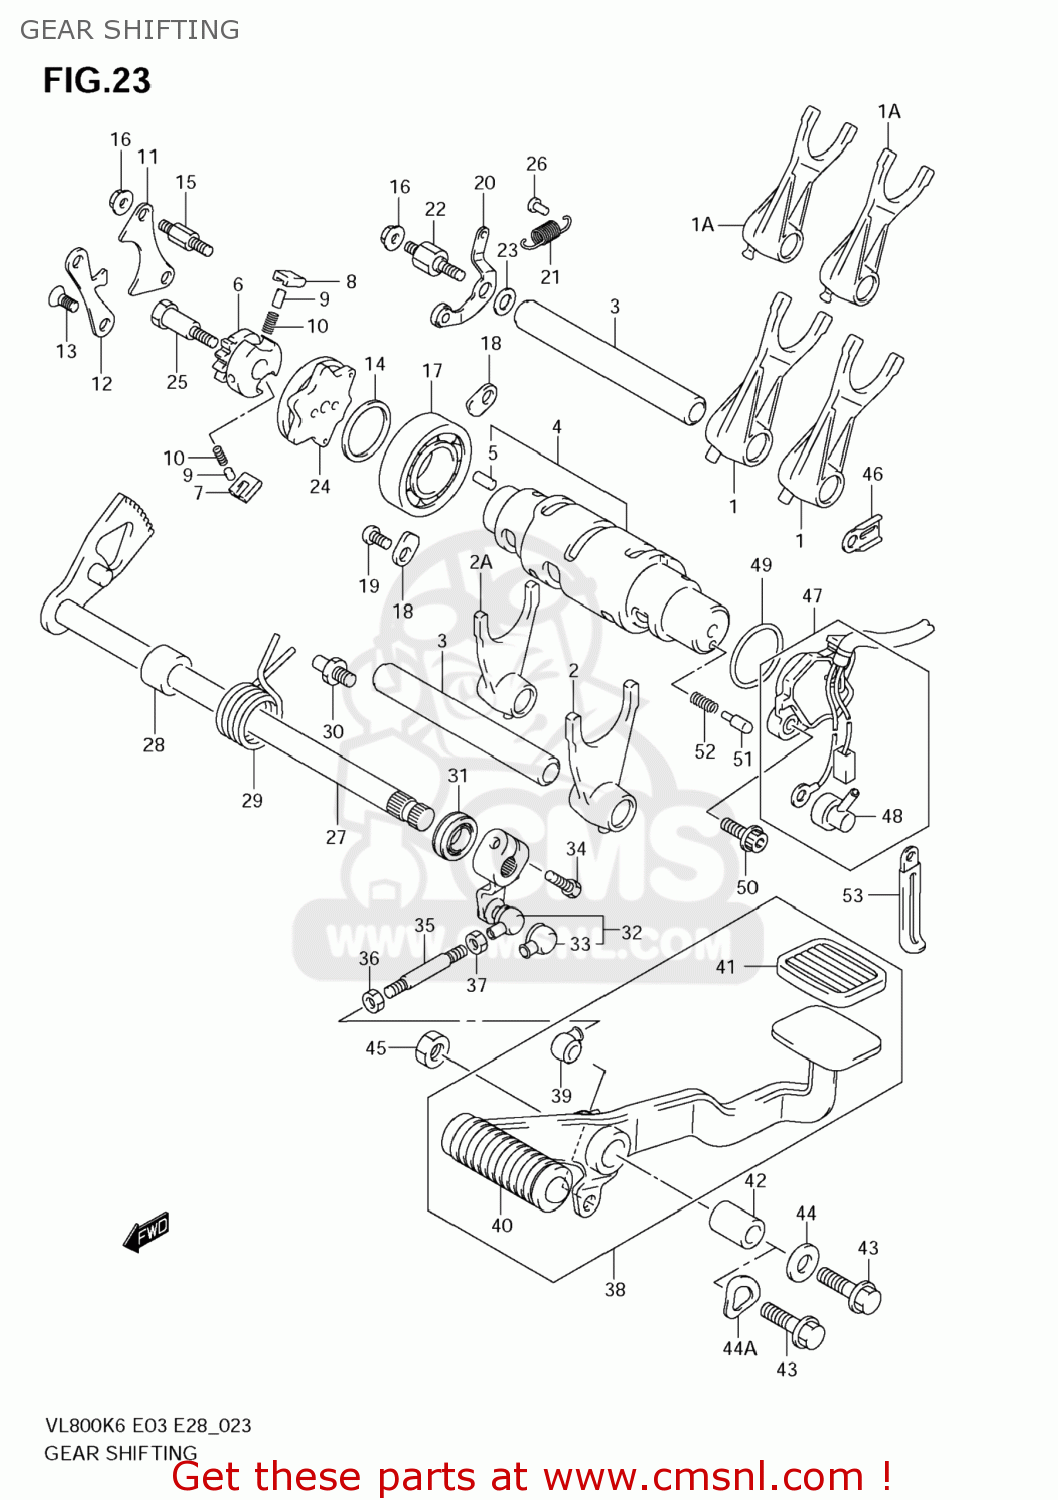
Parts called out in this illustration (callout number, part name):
1	FORK,GEAR SHIFT NO.1
1A	FORK,GEAR SHIFT NO.1
2	FORK,GEAR SHIFT NO.2
2A	FORK,GEAR SHIFT NO.2
3	SHAFT,GEAR SHIFT FORK(L:115)
4	CAM,GEAR SHIFT
5	PIN
6	GEAR,GEAR SHIFT CAM DRIVEN
7	PAWL,GEAR SHIFT NO.1
8	PAWL,GEAR SHIFT NO.2
9	PIN(5X8)
10	SPRING
11	LIFTER,GEAR SHIFT POLE
12	GUIDE,GEAR SHIFT CAM
13	SCREW(6X12)
14	WASHER(25X32X3)
15	BOSS,SHIFT POLE LIFTER
16	NUT
17	BEARING(25X47X8)
18	RETAINER
19	BOLT(6X12)
20	STOPPER,GEAR SHIFT CAM
21	SPRING
22	SUPPORT,CAM STOPPER ARM
23	WASHER
24	PLATE,GEAR SHIFT CAM
25	PIN,SHIFT CAM DRIVEN GEAR
26	RIVET
27	SHAFT,GEAR SHIFT
28	SPACER(12X20X15.3)
29	SPRING
30	STOPPER,GEAR SHIFT ARM
31	OIL SEAL
32	ARM,GEAR SHIFT LINK
33	COVER,DUST
34	BOLT
35	ROD,GEAR SHIFT LINK
36	NUT
37	NUT
38	LEVER ASSY,GEAR SHIFT
39	COVER,DUST
40	RUBBER
41	RUBBER,BRAKE PEDAL
42	SPSCER,GEAR SHIFT LEVER
43	BOLT(10X40)
44	WASHER (10.5X24X2.3)
44A	WASHER
45	NUT
46	CLAMP,GENERATOR LEAD WIRE
47	BASE ASSY,GEAR
48	CAP,OIL PRESSURE SWITCH
49	O RING(D:2.4,ID:26.2)
50	BOLT
51	PIN(5X15.5)
52	SPRING
53	CLAMP(L:45)
